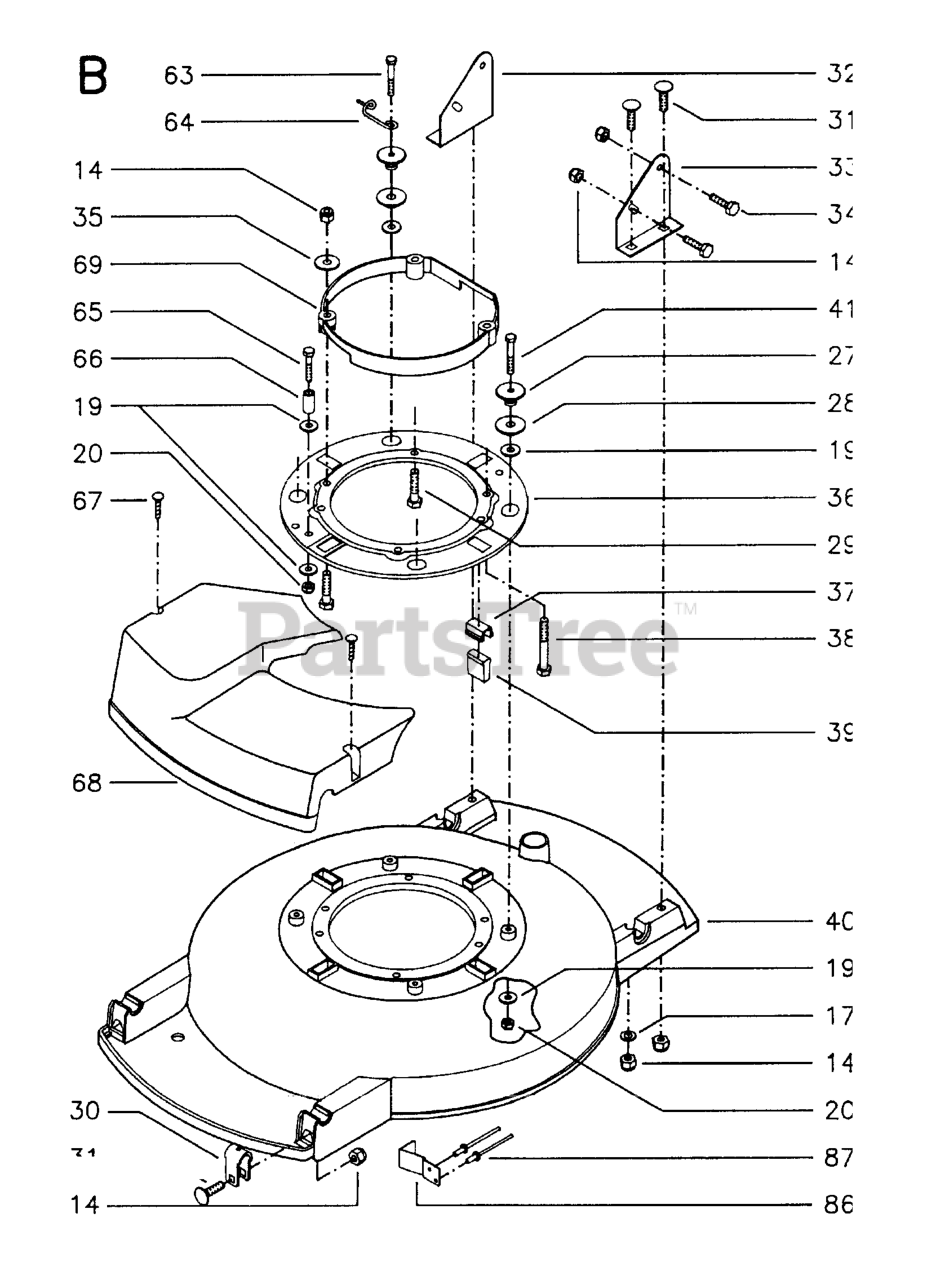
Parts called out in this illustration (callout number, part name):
14	LOCKNUT M8
17	WASHER - 15X7.3X1.6
20	LOCKNUT M6
28	RUBBER PIECE
30	BEARING HOLDER
32	HANDLE BRACKET
33	HANDLE BRACKET
34	BOLT - M8X16
39	DAMPER
65	BOLT FLANGE
